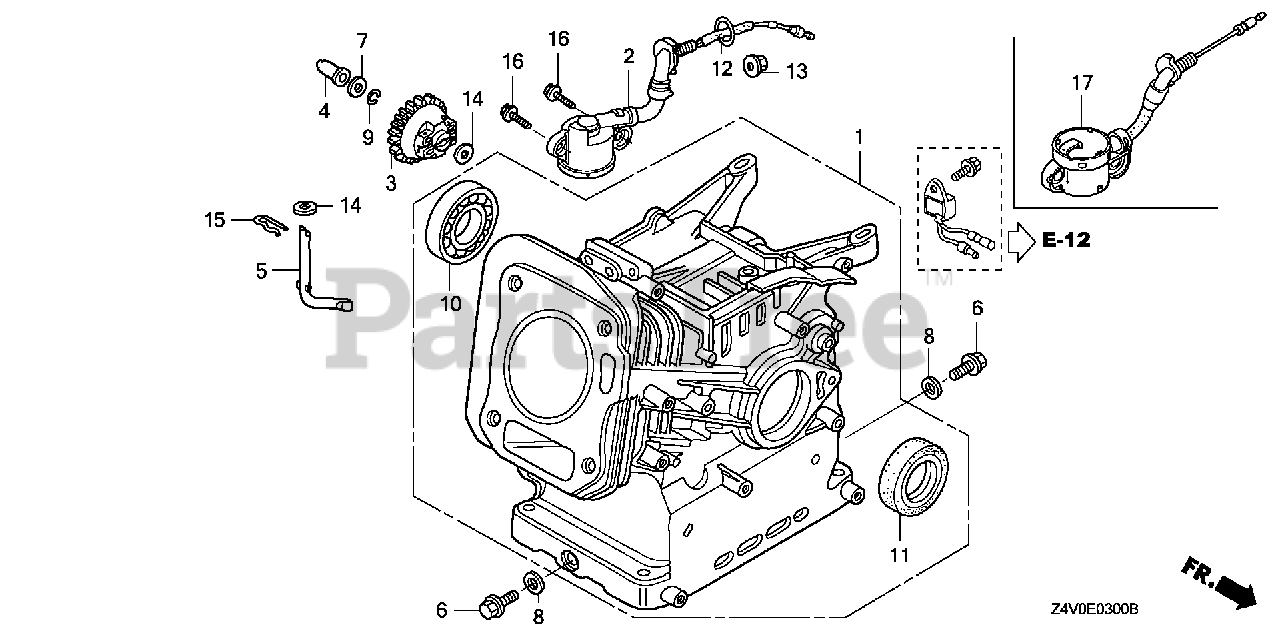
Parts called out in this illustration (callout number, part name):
1	CYLINDER ASSY.
3	GOVERNOR ASSY.
4	SLIDER, GOVERNOR
5	SHAFT, GOVERNOR ARM
6	BOLT, DRAIN PLUG
7	WASHER, THRUST (6MM)
8	WASHER, DRAIN PLUG (10.2MM)
9	CLIP, GOVERNOR HOLDER
10	BEARING, RADIAL BALL (6205TMB) (NTN)
10	BEARING, RADIAL BALL (6205) (NSK)
11	OIL SEAL (25X41X6) (NOK)
12	O-RING (13.5X1.5) (ARAI)
12	O-RING (14MM) (NOK)
13	NUT, FLANGE (10MM)
14	WASHER, PLAIN (6MM)
15	PIN, LOCK (8MM)
16	BOLT, FLANGE (6X12)
17	SWITCH ASSY., OIL LEVEL
